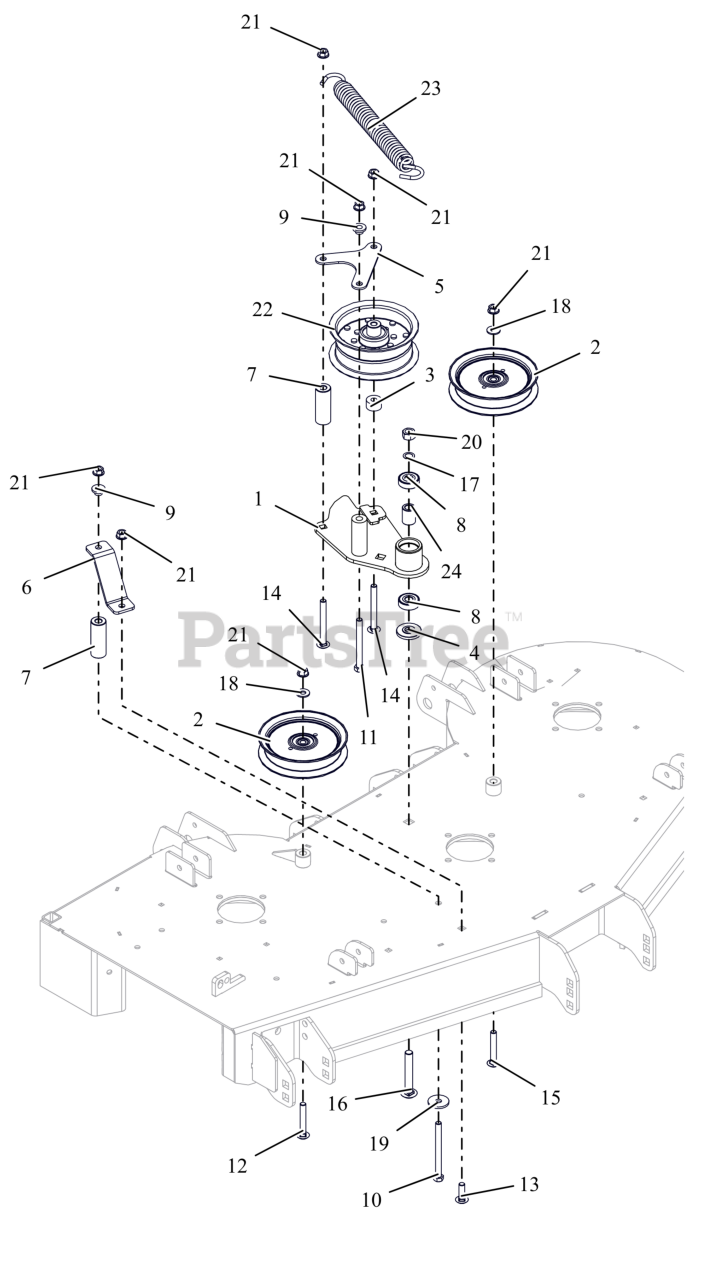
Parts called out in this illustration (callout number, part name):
1	WLDMT, IDLER ARM
2	IDLER, FLAT 5.00"
3	SPACER .390X1.000X.562
4	SPACER, IDLER ARM
5	BRKT, SUPPORT (BLACK)
6	BRKT, SPRG ANCHOR (BLACK)
7	SPCR, TUBE (BLACK)
8	BRG-BALL .500X1.38X.437
9	BSHG-FLG .385X.500X.875X.406
10	BLT, HEX 0.375-16X4.25 GR5 ZCC
11	BLT, HEX 0.375-16X3.75 GR5 ZCC
12	BLT,RHSN .38-16X2.50 G5 ZCC
13	BLT,RHSSN .38-16X1.25 G5 ZCC
14	BLT,RHSSN .38-16X3.50 G5 ZCC
15	BLT, RHSSN.38-16X2.50 G5 ZCC
16	BTL,RHSSN .500-13 X 3.25 G5 ZCC
17	WASHER, .500X.750X.020 THRUST
18	WSHR,FLT .375X.875X.083 ZCC
19	WSHR,FLT .406X1.375X.135 ZCC
20	NUT,LK-CTR .50-13 GA ZCC
21	NUT-LK-CTR-FLG .375-16 GF ZCC
22	PULLEY, FLAT 5.00X2.36X.375
23	SPRING, EXTENSION
24	SPACER .510 X .867 X 1.1485
